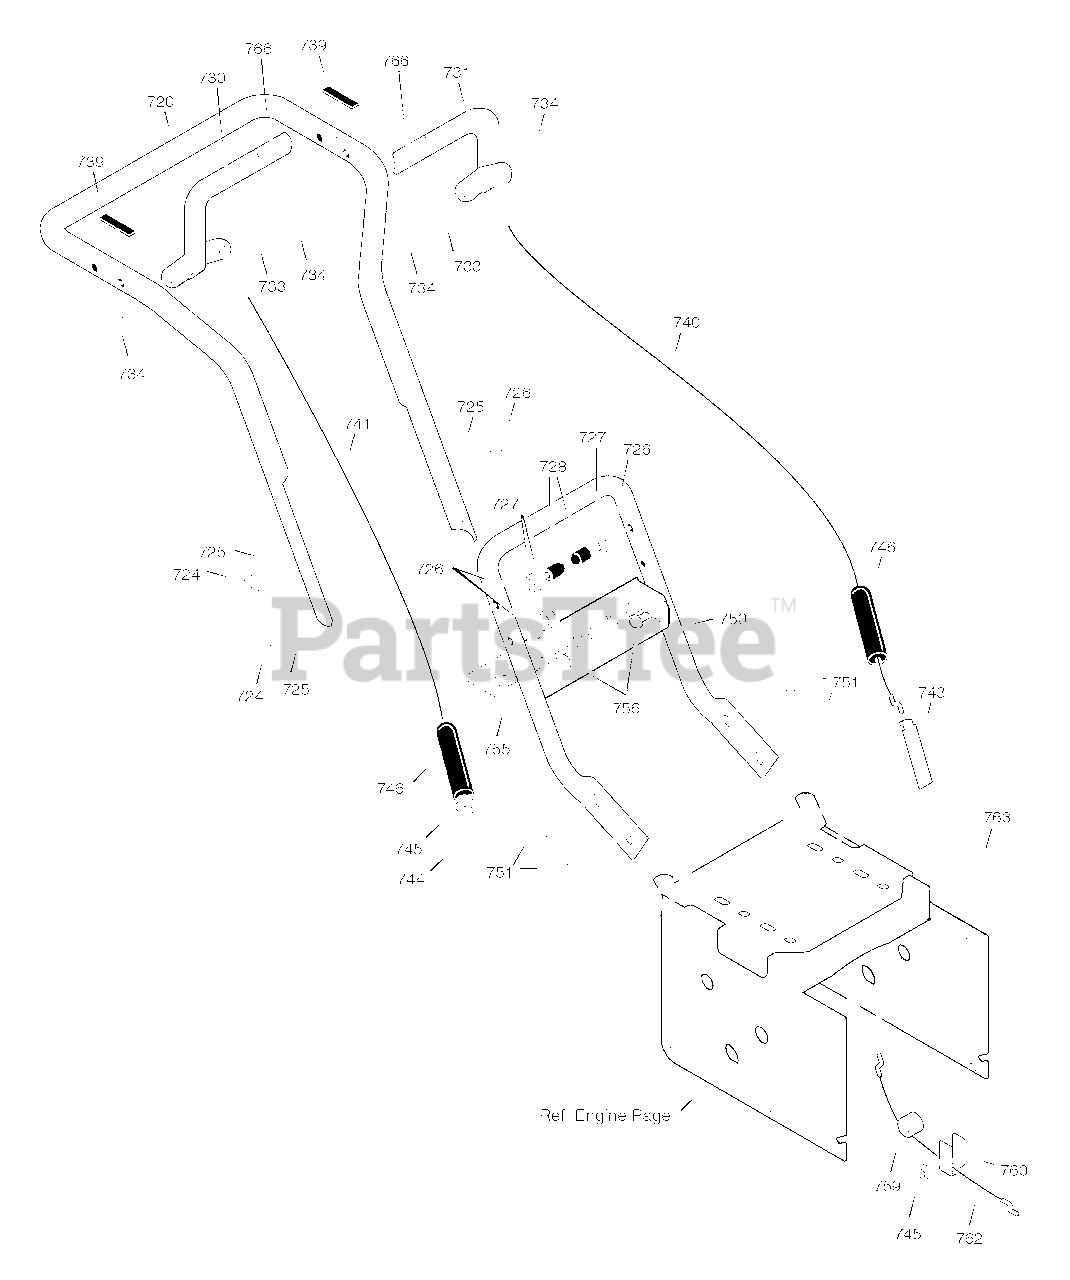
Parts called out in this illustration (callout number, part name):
720	HANDLE, UPPER
724	SCREW, 5/16-18 x 2.75
725	WASHER, FLAT
726	WASHER, SPTLK .31X.58X.08
727	NUT, 5/16-18 REGHEX
728	STOP, RED PLASTIC
730	CLUTCH HANDLE, RIGHT
731	CLUTCH HANDLE, LEFT
733	PIN, PIVOT CLUTCH
734	NUT, PUSH ON CAP
739	BUMPER, RECTANGLE
740	CABLE, CLUTCH 28.44L
741	CABLE, AUGER CLUTCH
743	BRACKET, CABLE ADJUSTER
744	SPRING, AUGER CLUTCH
745	NUT, 1/4-20
746	BOOT, CLUTCH SPRING
750	HANDLE, LOWER
751	SCREW, TAP 5/16-18 X .75
755	BRKT, GEAR SELECTOR
756	SCREW, 1/4-20 X 0.63
759	SPOOL-CABLE, AUGRT CLUTCH
760	BRACKET, CABLE SPOOL YZ
762	CABLE, LOWER DRIVE 12"
763	BOLT, HEX 1/4-20 X 1.50
